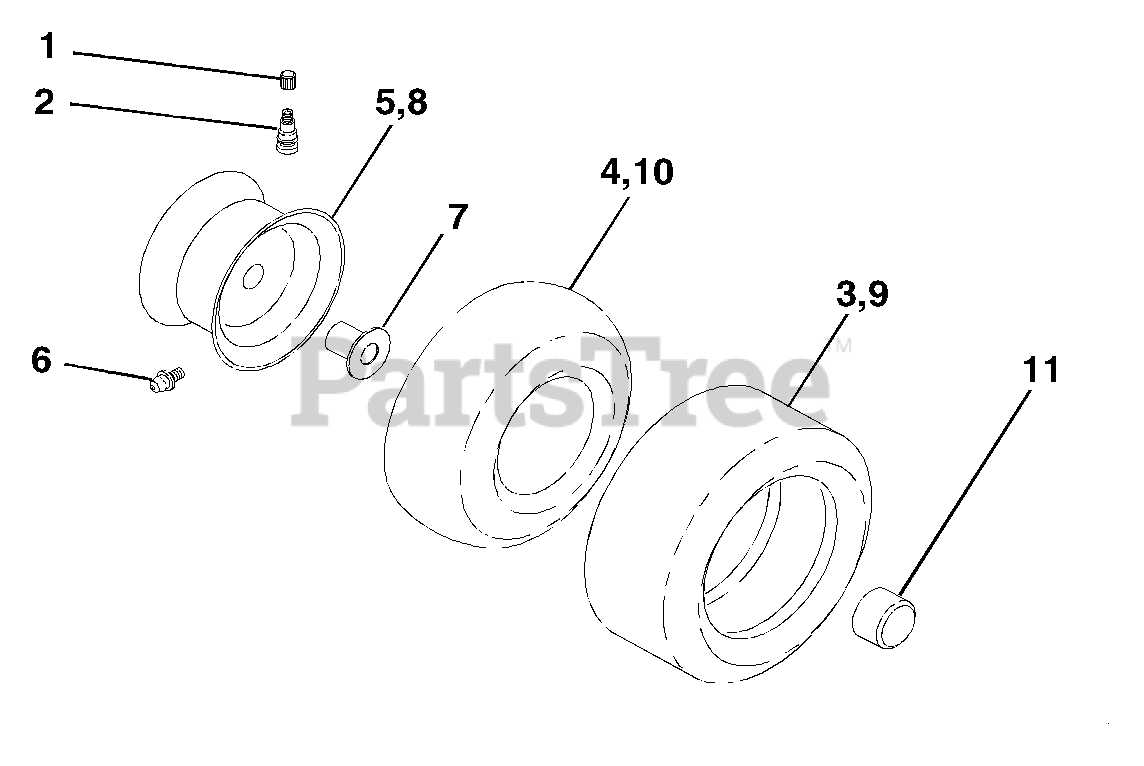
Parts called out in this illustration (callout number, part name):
1	Cap Valve Tire
2	Stem Valve
3	Tire F Ts 15 X 6 0 - 6 Service
4	Tube Front (Service Item Only)
5	Rim Asm 6"front Silver Service
6	Fitting Grease (Front Wheel Only)
7	Bearing Flange (Front Wheel Only)
8	Rim Asm 8"rear Silver Service
9	Tire R Ts 20x10-8 C Service
10	Tube Rear (Service Item Only)
11	Cap Axle Blk 1 50 X 1 00
